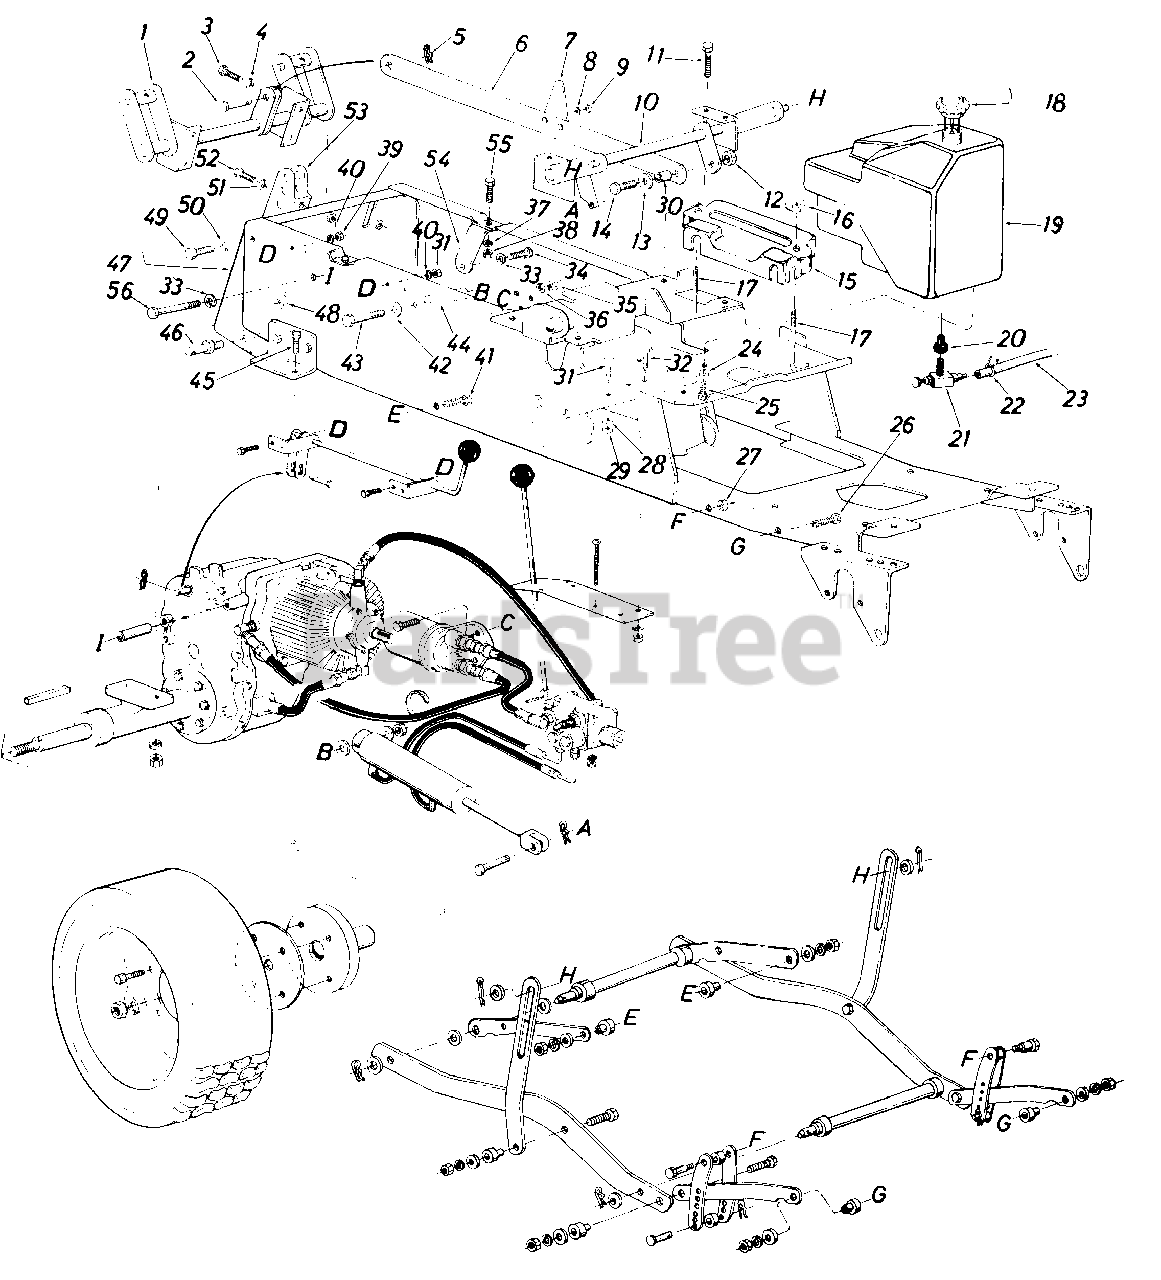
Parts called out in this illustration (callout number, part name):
3	Hex Scr. 3/8-16 x 1.00" Lg. Grade 5
4	L-Wash. 3/8" Scr. H.D.
5	Cotter Pin 1/8" Dia. x 1.25" Lg. *
8	L-Wash. 5/16" Scr.
9	Hex Nut 5/16-18 Thd.
12	Hex Cent. L-Nut 1/2-20 Thd.
13	Fl-Wash.
14	Hex Scr. 1/2-20 x 1.25" Lg.
15	Battery Cover
16	Wing Nut 1/4-20 Thd.
17	Battery Hold Down Rods
18	Gas Tank Cap
19	Gas Tank Ass'y.
20	Bushing
21	Fuel Shut-Off Valve with Screen
22	Gas Line Clamp 7/16"
23	Gas Line 30" Lg.
24	Bell-Wash.
25	Hex Scr. 1/4-20 x .38" Lg.
26	Hex Scr. 3/8-24 x 1.50" Lg.
27	Hex Nut 3/8-16 Thd.
28	L-Wash. 3/8" Scr.
29	Hex Nut 3/8-16 Thd.
30	Push Bar Sleeve
31	Hex Scr. 3/8-16 x 1.00 Lg. Grade 5
32	Hex Scr. 5/16-18 x .75" Lg.
33	L-Wash. 1/2" Scr.
34	Hex Scr. 1/2-13 x 1.25" Lg.
35	Hex Nut 5/16-18 Thd.
36	L-Wash. 5/16" Scr.*
37	L-Wash. 3/8" Scr. H.D.
38	Hex Nut 3/8-16 Thd.
39	Hex Nut 1/4-20 Thd.
40	L-Wash. 1/4" Scr.
41	Hex Scr. 3/8-24 x 1.50" Lg.
42	Fl-Wash. .50" I.D. x 1.25 O.D.
43	Hex Scr. 1/2-20 x 3-1/2" Lg. Grade 5
44	Spacer for Cylinder
45	Hex Scr. 3/8-16 x 1.75" Lg.
46	Link Clevis Pin
49	Hex Scr. 3/8-16 x .75" Lg. Grade 5
50	L-Wash. 3/8" Scr.
51	L-Wash. 3/8" Scr. H.D.
52	Hex Scr. 3/8-16 x .75" Lg. Grade 5
54	Transmission Brace
55	Hex Scr. 3/8-16 x 1.00" Lg.
56	Hex Scr. 1/2-13 x 2.75" Lg.
